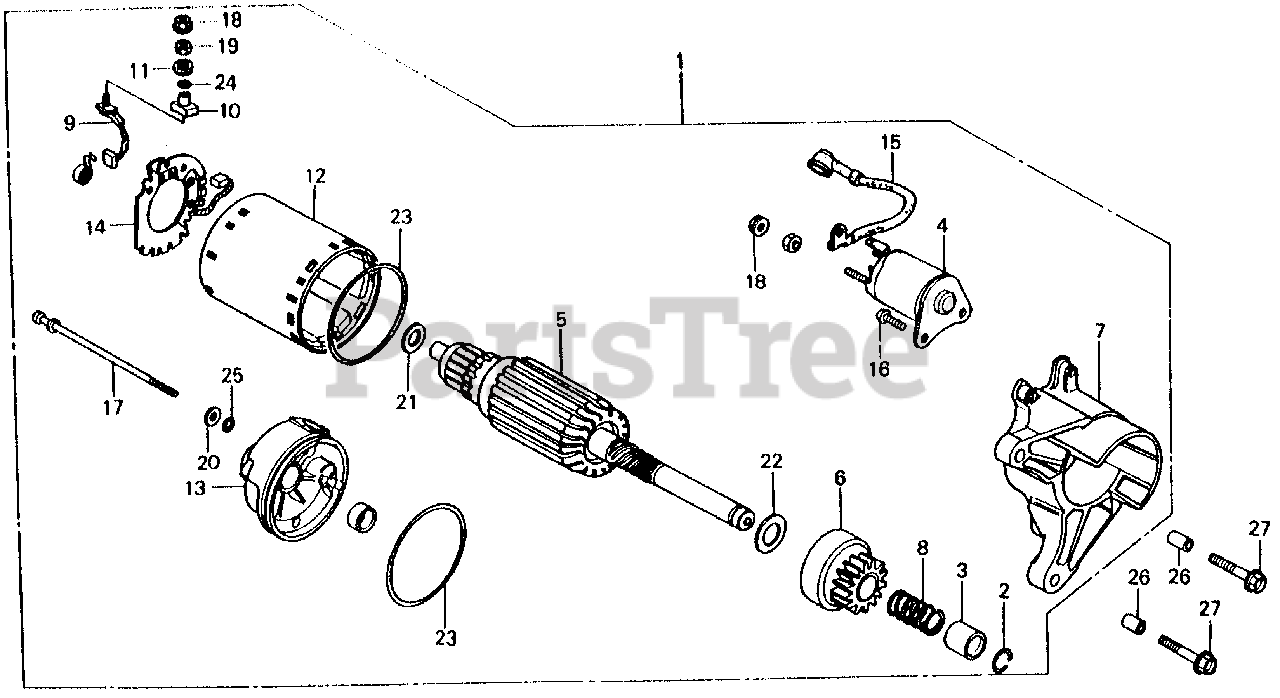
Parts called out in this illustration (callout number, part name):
1	MOTOR ASSY., STARTER
2	RING, SNAP
3	COLLAR, CLUTCH
4	CONTACTOR ASSY.
5	ARMATURE
6	CLUTCH, OVERRUNNING
7	HOUSING, DRIVE SIDE
8	SPRING, BRUSH
8	SPRING
9	BRUSH
10	BUSHING, INSULATION
11	BUSHING, INSULATION
12	YOKE
13	FRAME, STARTER END
14	PLATE, BRUSH HOLDER
15	WIRE, WATER COVER
16	BOLT
17	BOLT, THROUGH (NOT AVAILABLE)
18	NUT
19	NUT
20	WASHER, STEEL PLATE
21	WASHER
22	WASHER
23	O-RING
24	O-RING
25	O-RING
26	PIN A, DOWEL (10X16)
27	BOLT, FLANGE (8X35)
